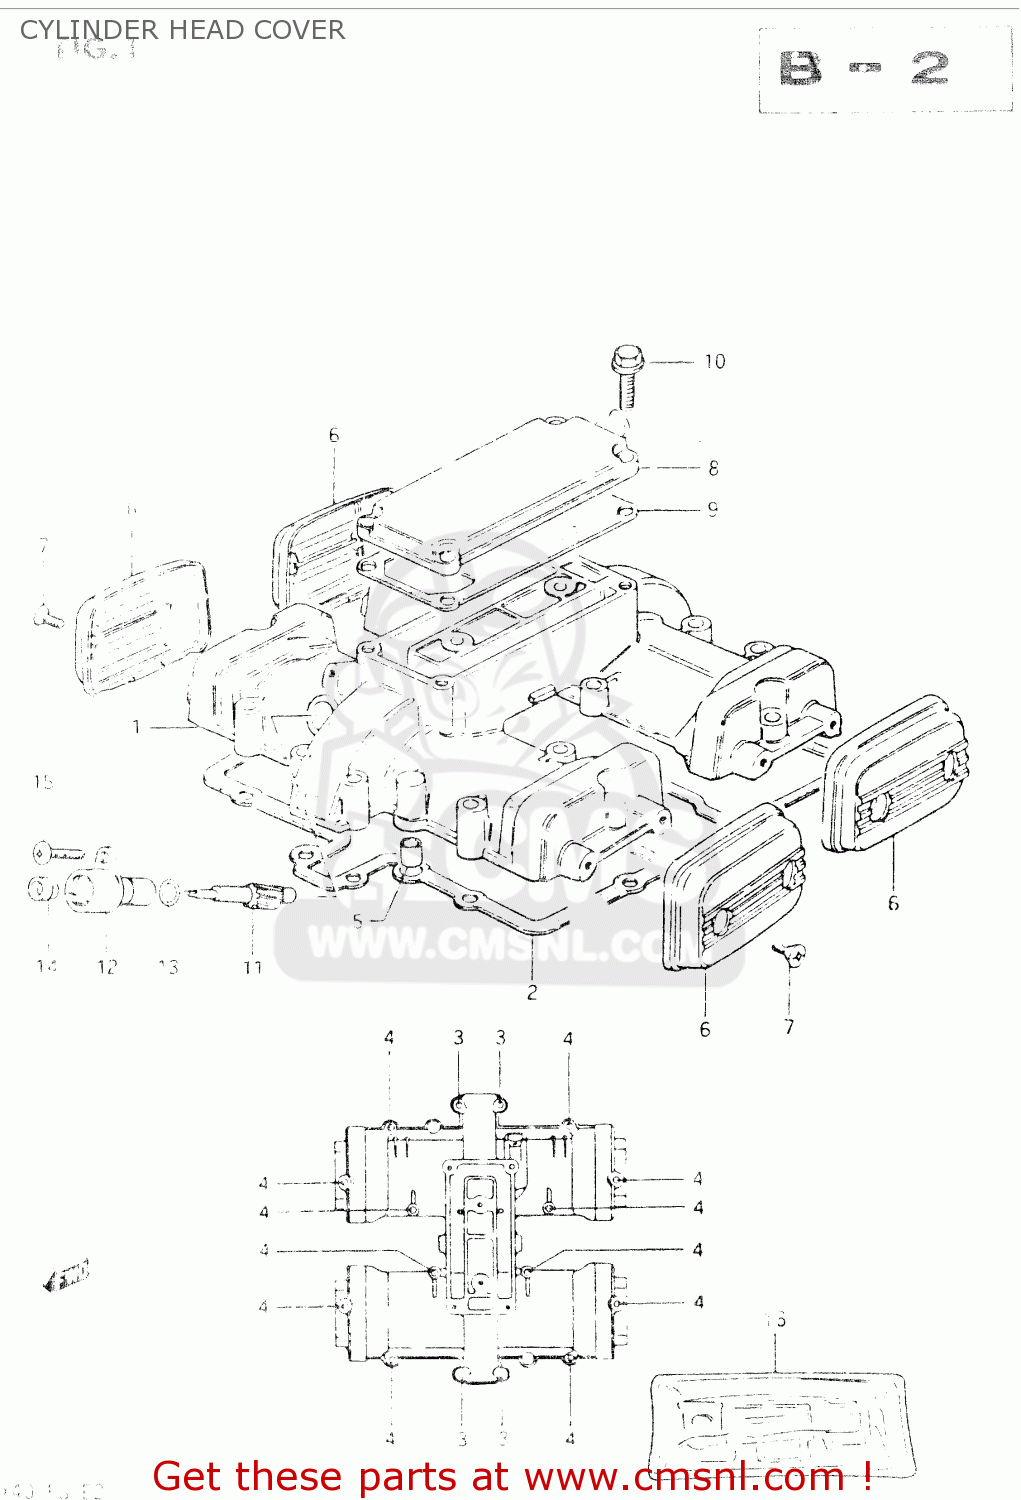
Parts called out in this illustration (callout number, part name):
1	COVER, CYLINDER HEAD
2	GASKET (MCA)
3	BOLT 6X35
4	BOLT 6X30
5	PIN(6.2X8X11)
6	CAP,CYLINDER HEAD COVER
7	SCREW(5X12)
8	COVER,BREATHER
9	GASKET (MCA)
10	BOLT
11	GEAR,TACHOMETER DRIVEN
12	SLEEVE,TACHOMETER DRIVE GEAR
13	SEAL,TACHOMETER DRIVEN
14	SEAL,OIL(5X12X8)
15	SCREW(5X12)
16	GASKET SET
